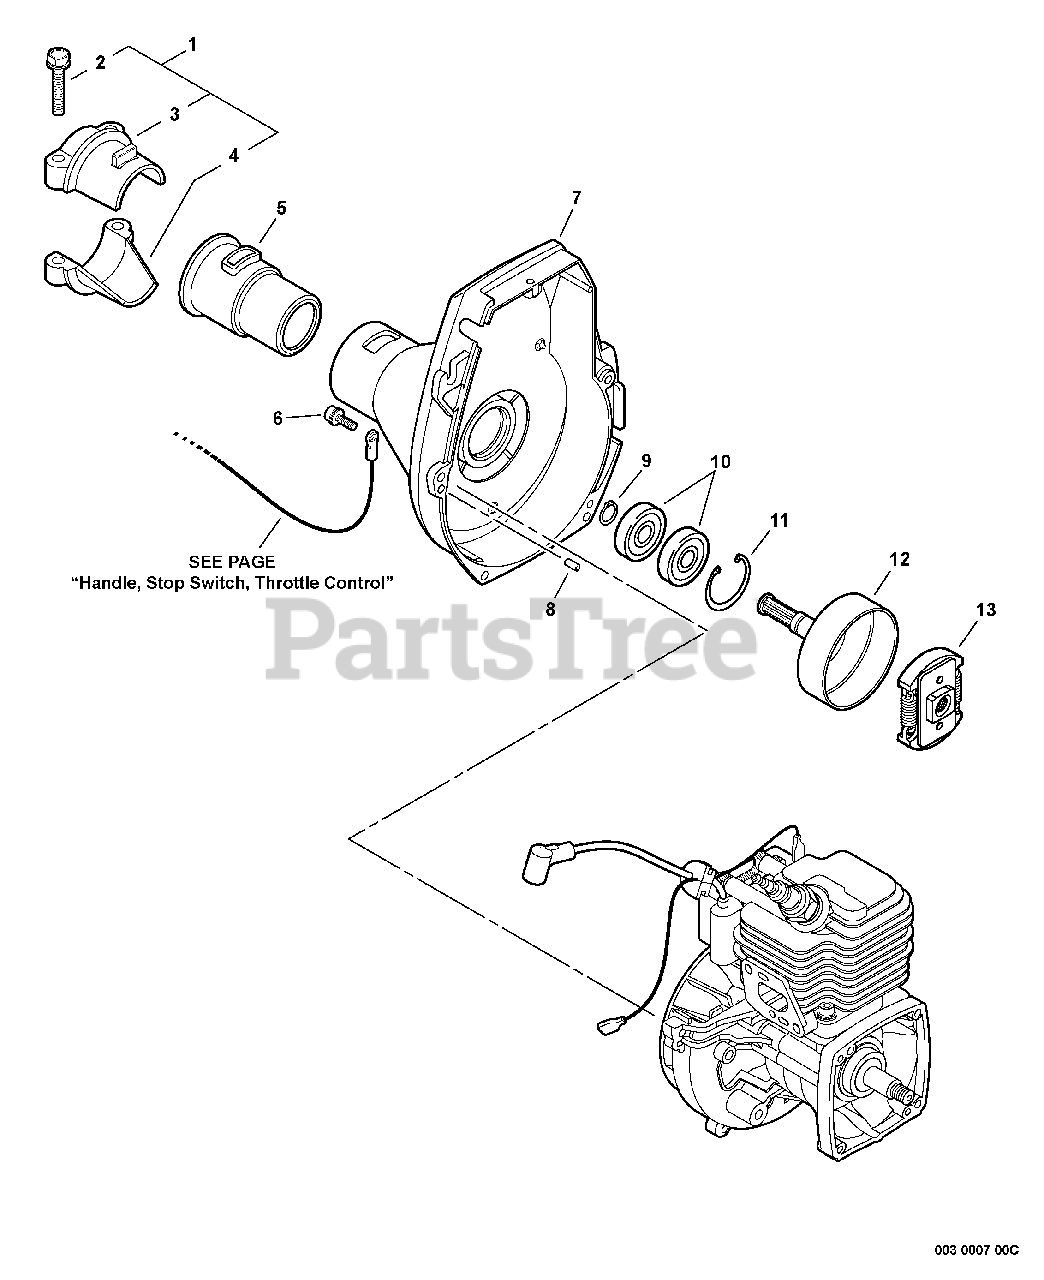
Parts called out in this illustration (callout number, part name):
1	HOLDER KIT
2	BOLT - 5×25
3	HOLDER, MAIN PIPE - UPPER
5	CUSHION
6	BOLT 4×16
7	COVER ASSY, FAN
8	PIN, LOCATING 4
9	RING, RETAINING - 12
10	BEARING, BALL 6001
11	RING, SNAP 28
12	DRUM, CLUTCH
13	CLUTCH ASSY
